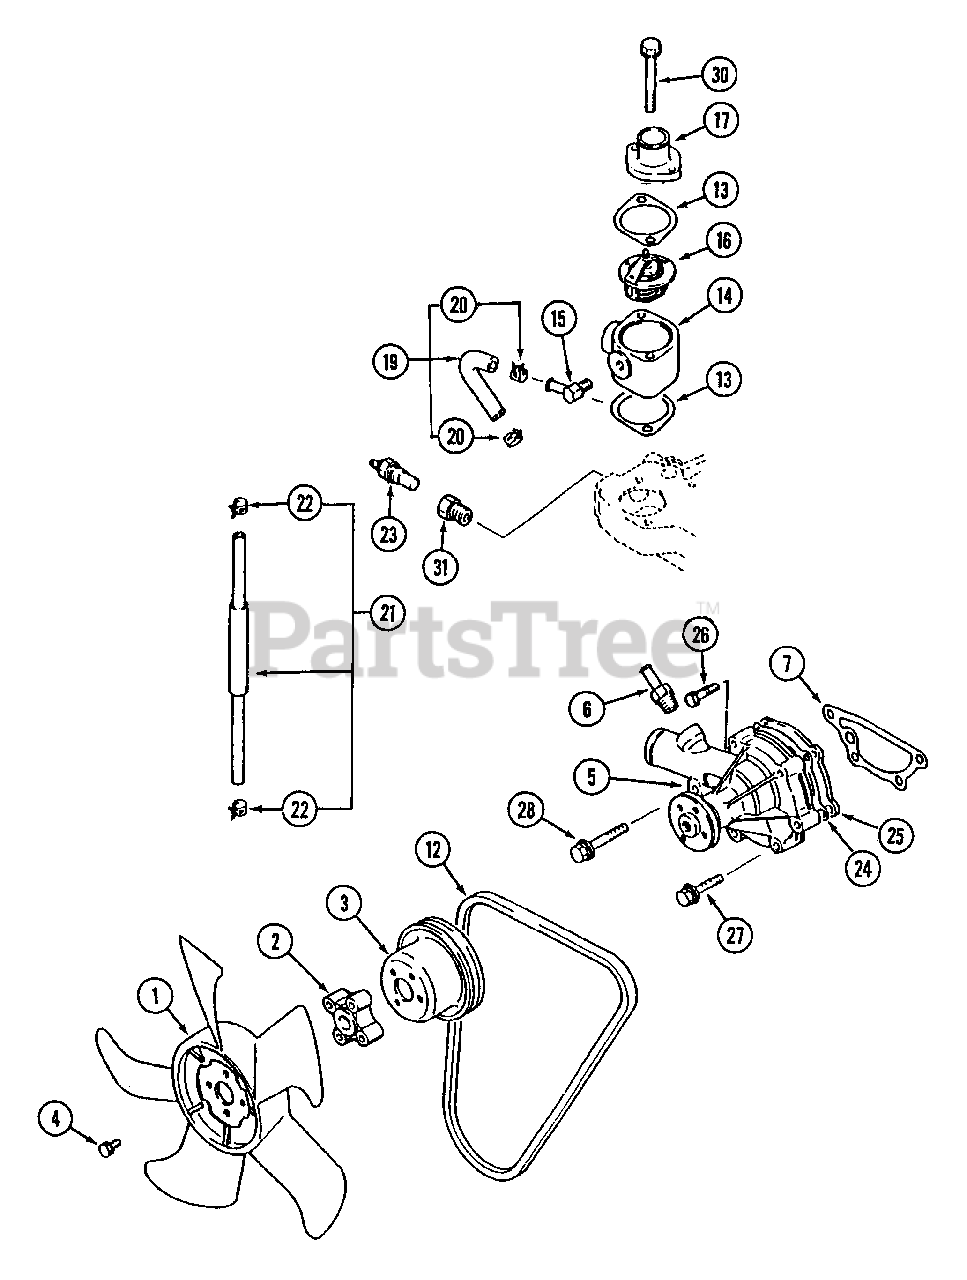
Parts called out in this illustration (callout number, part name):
1	Fan, Cooling
2	Spacer, Fan
3	Pulley, Water Pump
4	Bolt, w/Washer
5	Water Pump Ass'y.
6	Nipple, Base
7	Gasket, Water Pump
13	Gasket
14	Fitting, Thermostat
15	Joint, Water Hose
17	Fitting, Water Outlet
19	Hose Ass'y., Water
21	Hose Ass'y., Water Drain
22	Clamp, Hose
23	Unit, Thermo.
24	Gasket, Water Pump
25	Plate, Water Pump
26	Bolt, w/Washer
27	Bolt, Washer Ass'y.
28	Bolt, Washer Ass'y.
30	Bolt, Washer Assembled
31	Joint, Thermo. Gauge Unit
